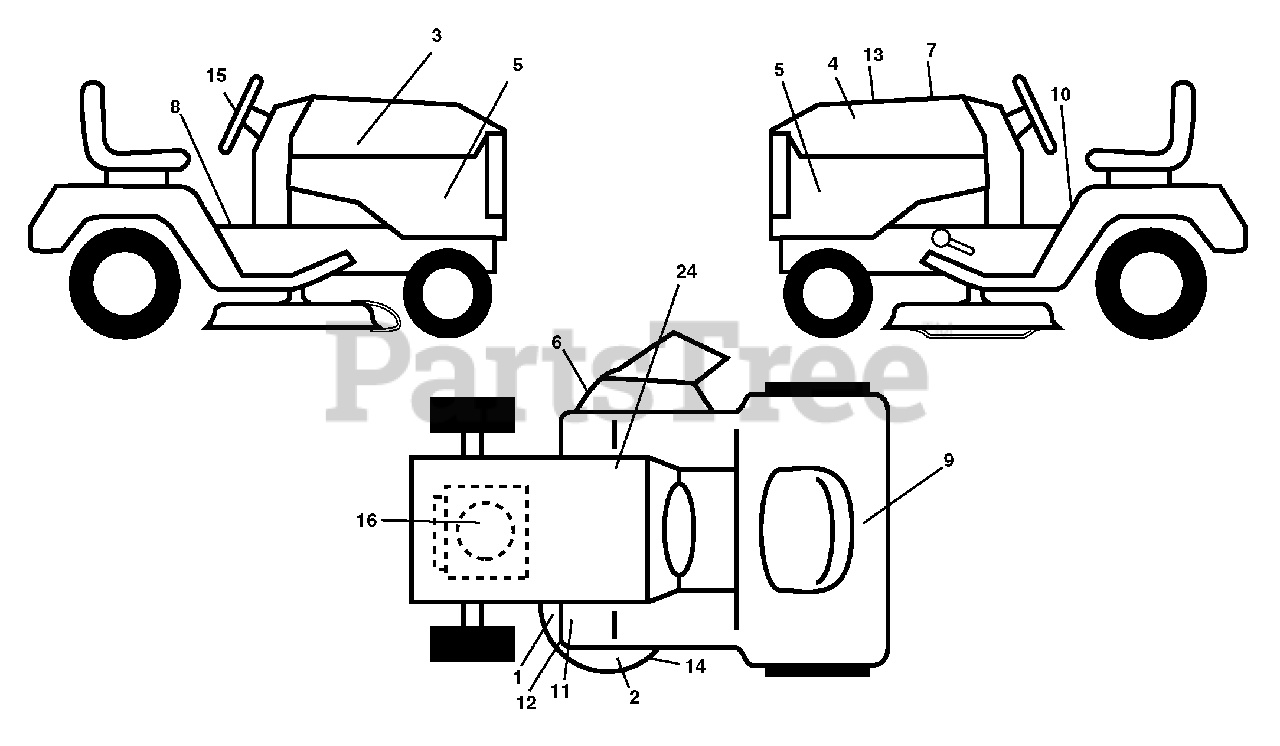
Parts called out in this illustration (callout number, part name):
1	Decal, Deck Caution
2	Decal, Deck Hvy Duty
3	Decal, Hood RH
4	Decal, Hood LH
5	Decal, Side Panel
6	Decal, Warning
7	Decal, Cust. Resp.
8	Decal, Operator
9	Decal, Fender
10	Decal, Danger
11	Decal, Foot Rest
12	Decal, MWR DCK Upstop
13	Decal, Replacement
14	Decal, V-Belt Schematic
15	Decal, Ins. Strg Whl
16	Decal, Engine HP
24	Decal, Btry Dngr/Psn
